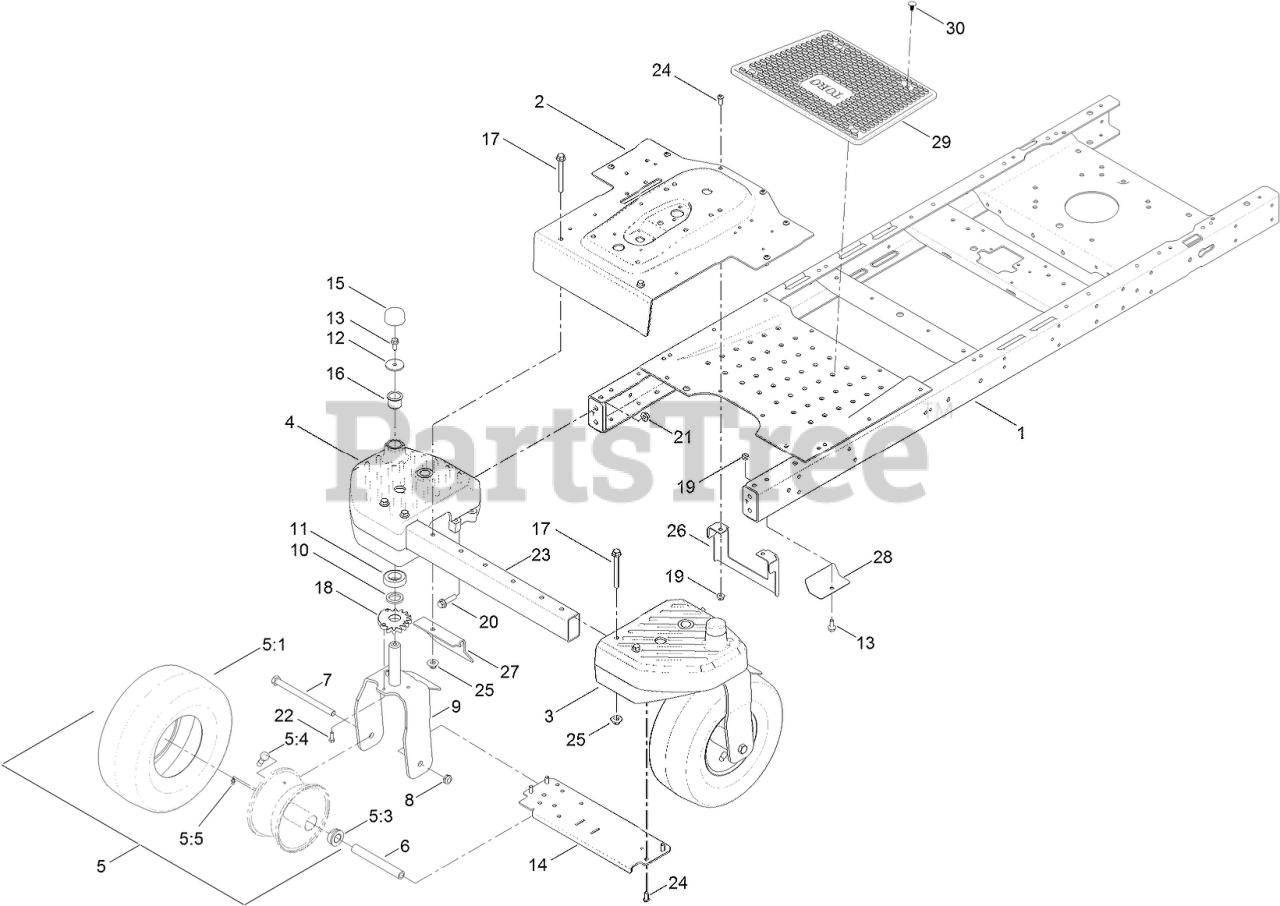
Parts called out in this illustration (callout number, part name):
1	FRAME ASM
2	PAN-STEER, FRONT
3	HOUSING-SPINDLE, LH
4	HOUSING-SPINDLE, RH
5	13 INCH WHEEL AND TIRE ASM
5:1	TIRE-13 Inch
5:3	BUSHING-FLANGE
5:4	STEM-VALVE
5:5	FITTING-GREASE
6	SPANNER
7	SCREW-HH
8	NUT-LOCK, NI
9	CASTER FORK ASM
10	WASHER-THRUST
11	BEARING-BALL
12	WASHER-FLAT
13	SCREW-HHF
14	PLATE-BRIDGE, NARROW
15	CAP-CASTER
16	BUSHING-PIVOT
17	SCREW-HHF
18	GEAR-WHEEL, 15 TEETH
19	NUT-HF, NI
20	SCREW-HHF
21	NUT-HF, NI
22	SCREW-HH
23	TUBE-FRONT, NARROW
24	SCREW-HSBH
25	NUT-FLANGE, NI
26	BRACKET-UPSTOP
27	GUARD-FRONT
28	PLATE-GUARD
29	MAT-FLOOR
30	PLUG-PLASTIC
